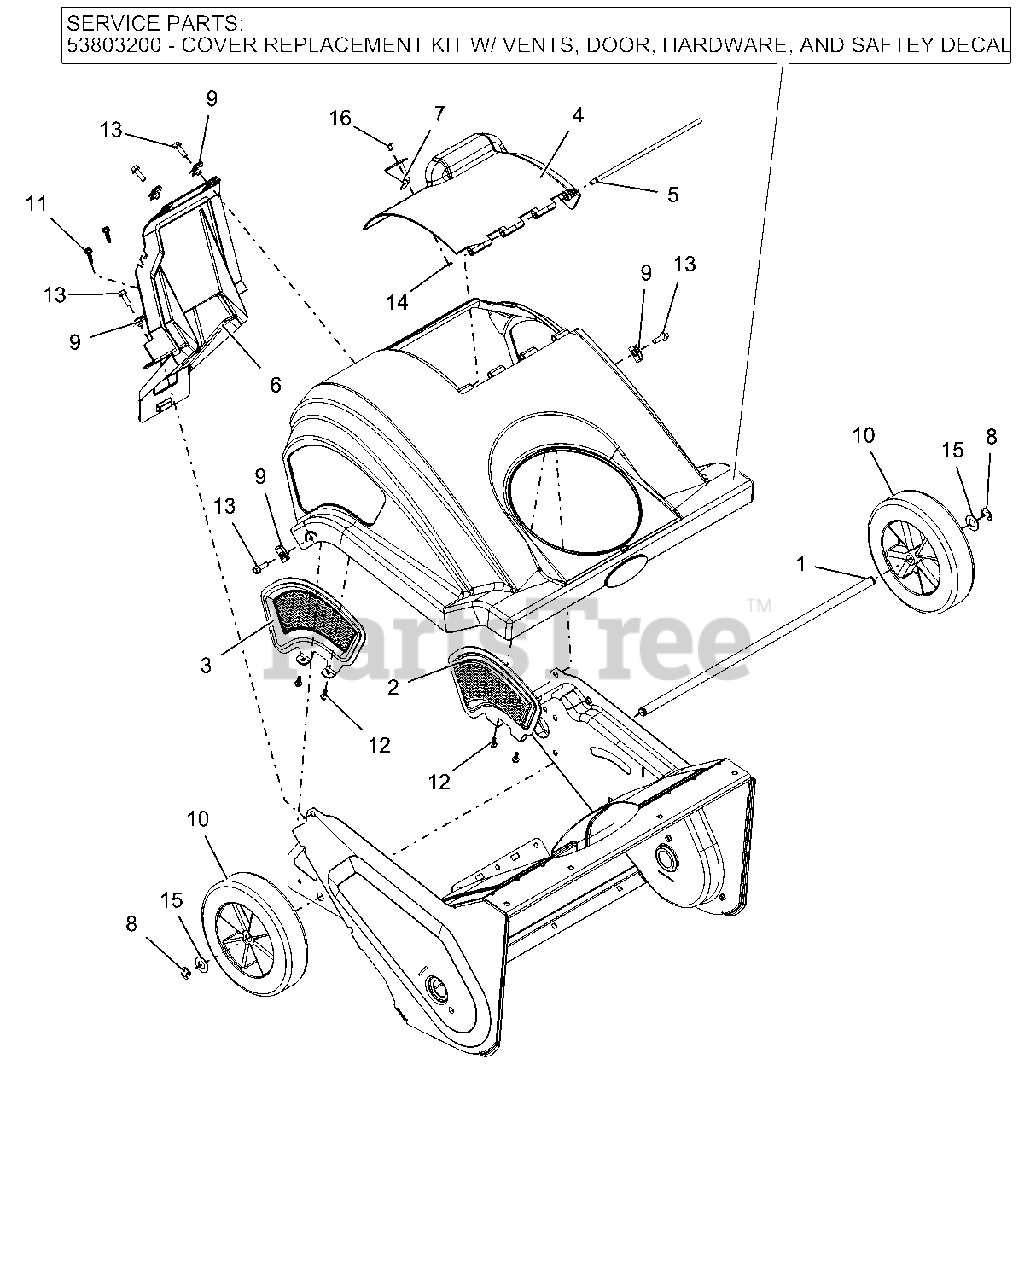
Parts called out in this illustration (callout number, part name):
1	SHAFT, AXLE
2	VENT, COVER LEFT
3	RIGHT VENT, COVER
4	DOOR, COWEL COVER
5	ROD, COVER, SINGLE STAGE
6	COVER, BACK ELECTRIC START
7	TAB, LATCH
8	RG-RTNG-EXT .500X.042 (E)
9	NUT-RTNR .25-20X.56
10	WHL 7.50" .50 BORE, 1.50 HUB
11	SCR-TAP #12X.75 BOSS INDHXHD
12	SCR-TAP #10X.50 BOSS INDHXHD
13	BLT-HEX .25-20X.75 HWH YZ GR5
14	WSHR-FL-STL .196X.500X.06 YZ
15	WSHR-FL-STL.531X1.00X.063 YWZC
16	RVT-POP .187 YZ
17	KIT, COWL REPLACEMENT
